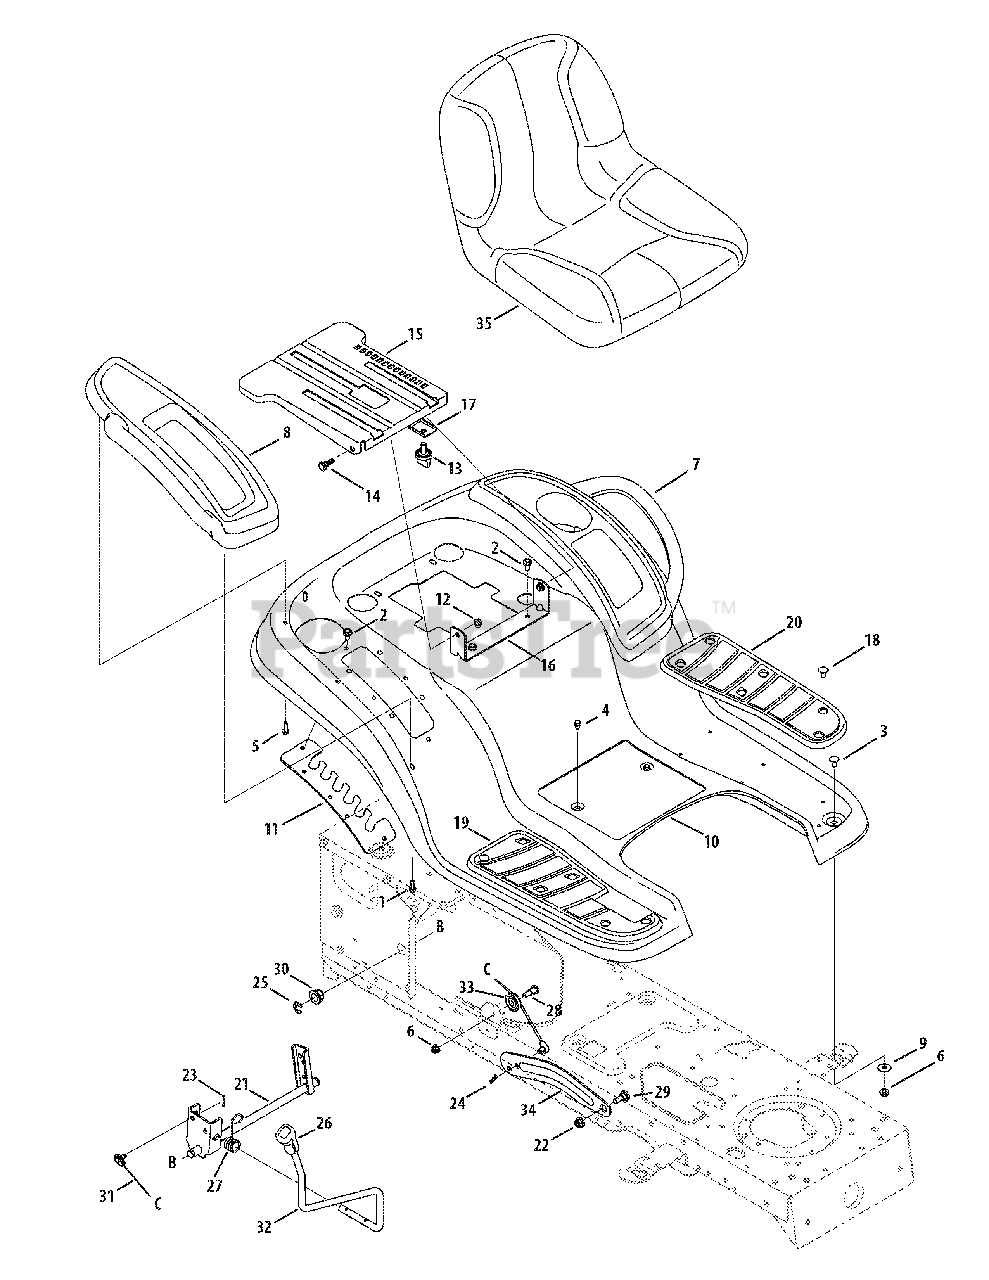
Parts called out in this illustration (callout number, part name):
1	Hex Screw, 1/4-15 x .50
2	Screw, 5/16-18 x.750
3	Carriage Bolt, 5/16-18 x.750
4	Screw, 1/4-20 x.500
5	Self-tapping Screw, 1/4-15 x.75
6	Flange Lock Nut, 5/16-18
7	LH Fender Cover
8	RH Fender Cover
9	Flat Washer,.349 x 1.0 x.063
10	Fender R-Style
11	Lift Adjustment Bracket
12	Nut, Flange Lock, 5/16-18, Gr5
13	Knob, 3/8-16 x .875
14	Shoulder Screw,.437 x.286
15	Seat Mount Bracket
16	Seat Pivot Bracket
17	Seat Knob Adjust Bracket
18	Foot Pad Clips
19	RH Foot Pad
20	LH Foot Pad
21	Lift Assembly Shaft
22	Flange Lock Nut, 3/8-16
23	Hairpin Clip
24	Cotter Pin
25	E-Ring
26	Handle Grip
27	Torsion Spring
28	Shoulder Screw, 3/8-16 .496 x 2.50
29	Shoulder Screw, 3/8-16 .500 X .270
30	Hex Flange Bearing
31	Lift Cable, 16.16
32	Lift Handle
33	Roller Pulley
35	High Back Seat, Gray
